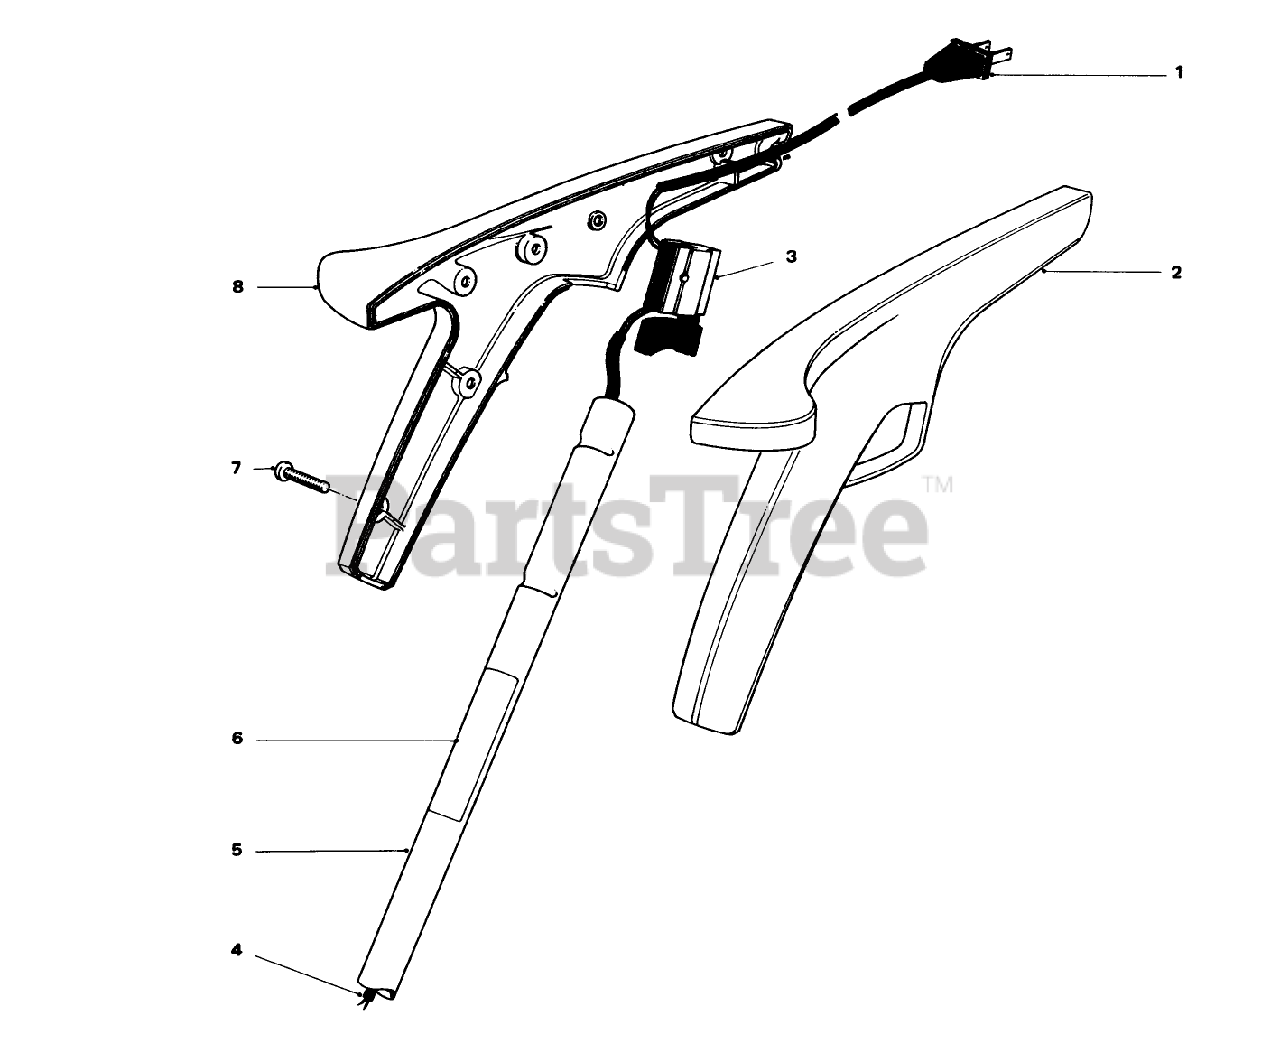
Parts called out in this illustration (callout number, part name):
1	Power Cord
2	LH HANDLE GRIP
3	SWITCH SINGLE SPEED
4	Wiring Harness
6	REPLACEMNT SERIAL PLT
7	Screw
8	Grip-Right Hand
